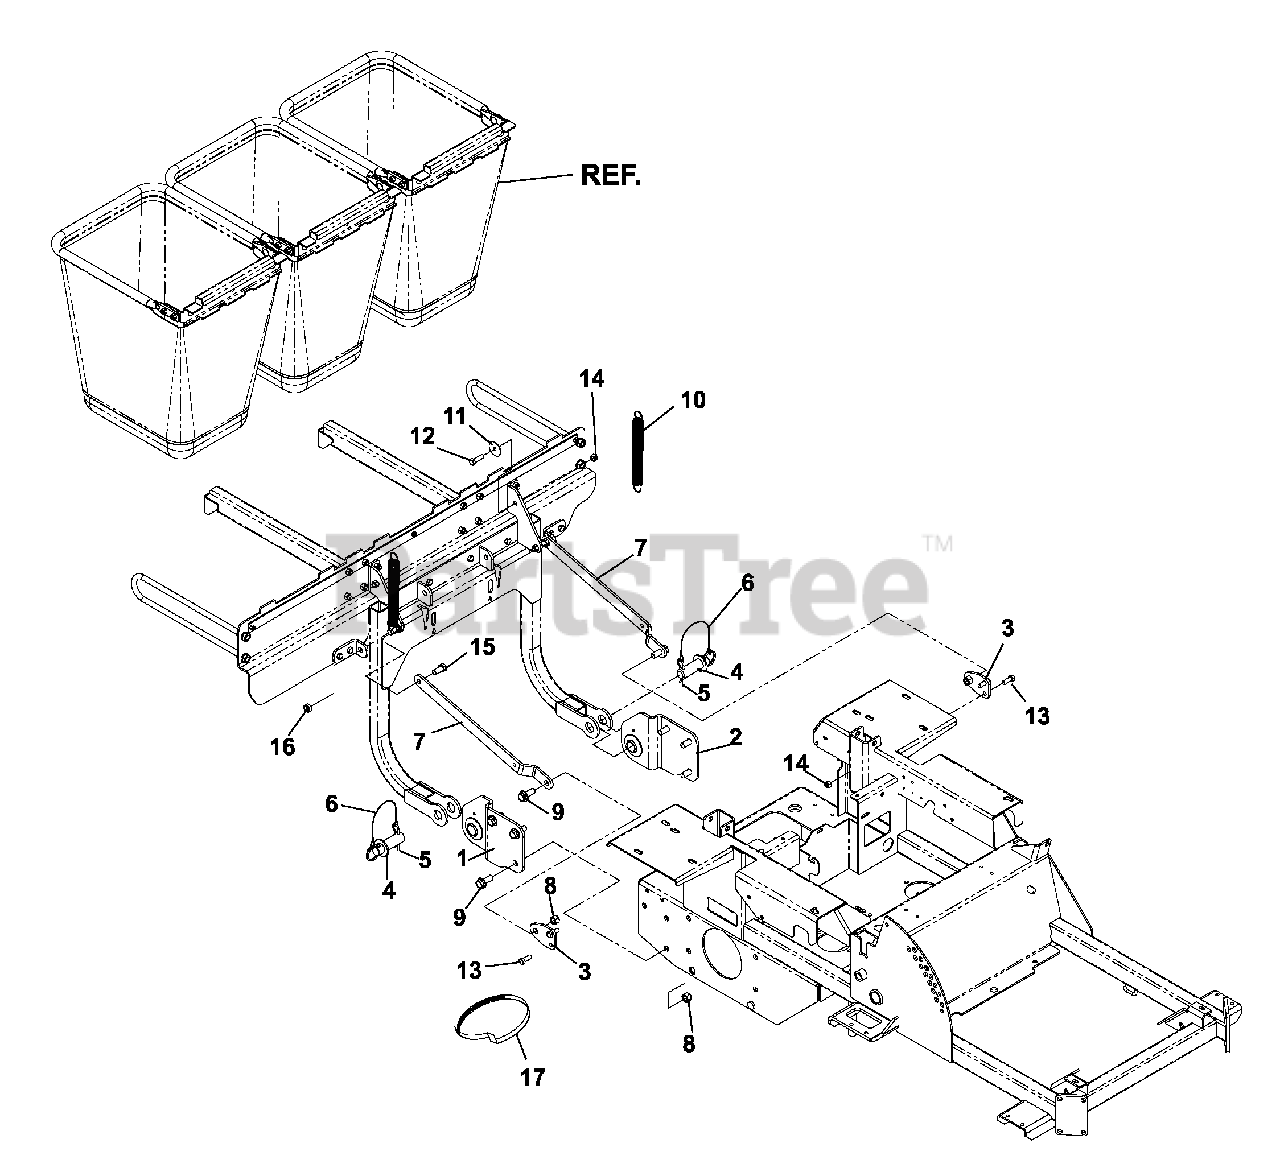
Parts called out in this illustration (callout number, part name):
1	HITCH BRACKET WLDMT, RT, MID
2	HITCH BRACKET WLD
3	SUPPORT BRACKET
4	HITCH PIN
5	HAIRPIN
6	LANYARD
8	NUT 1/2-13 HEX NYLOC ZD
9	HCS 1/2C X 1 1/4 SERRATED HEAD
11	WASHER, FRICTION
12	HCS 3/8C X 1 1/4 GR5
13	HCS 3/8C X 1
14	NUT 3/8-16 NYLOC
15	HHCS 1/2-13 X 1
16	NUT, 1/2-13 THIN PROF NYL
17	HOSE CLAMP
